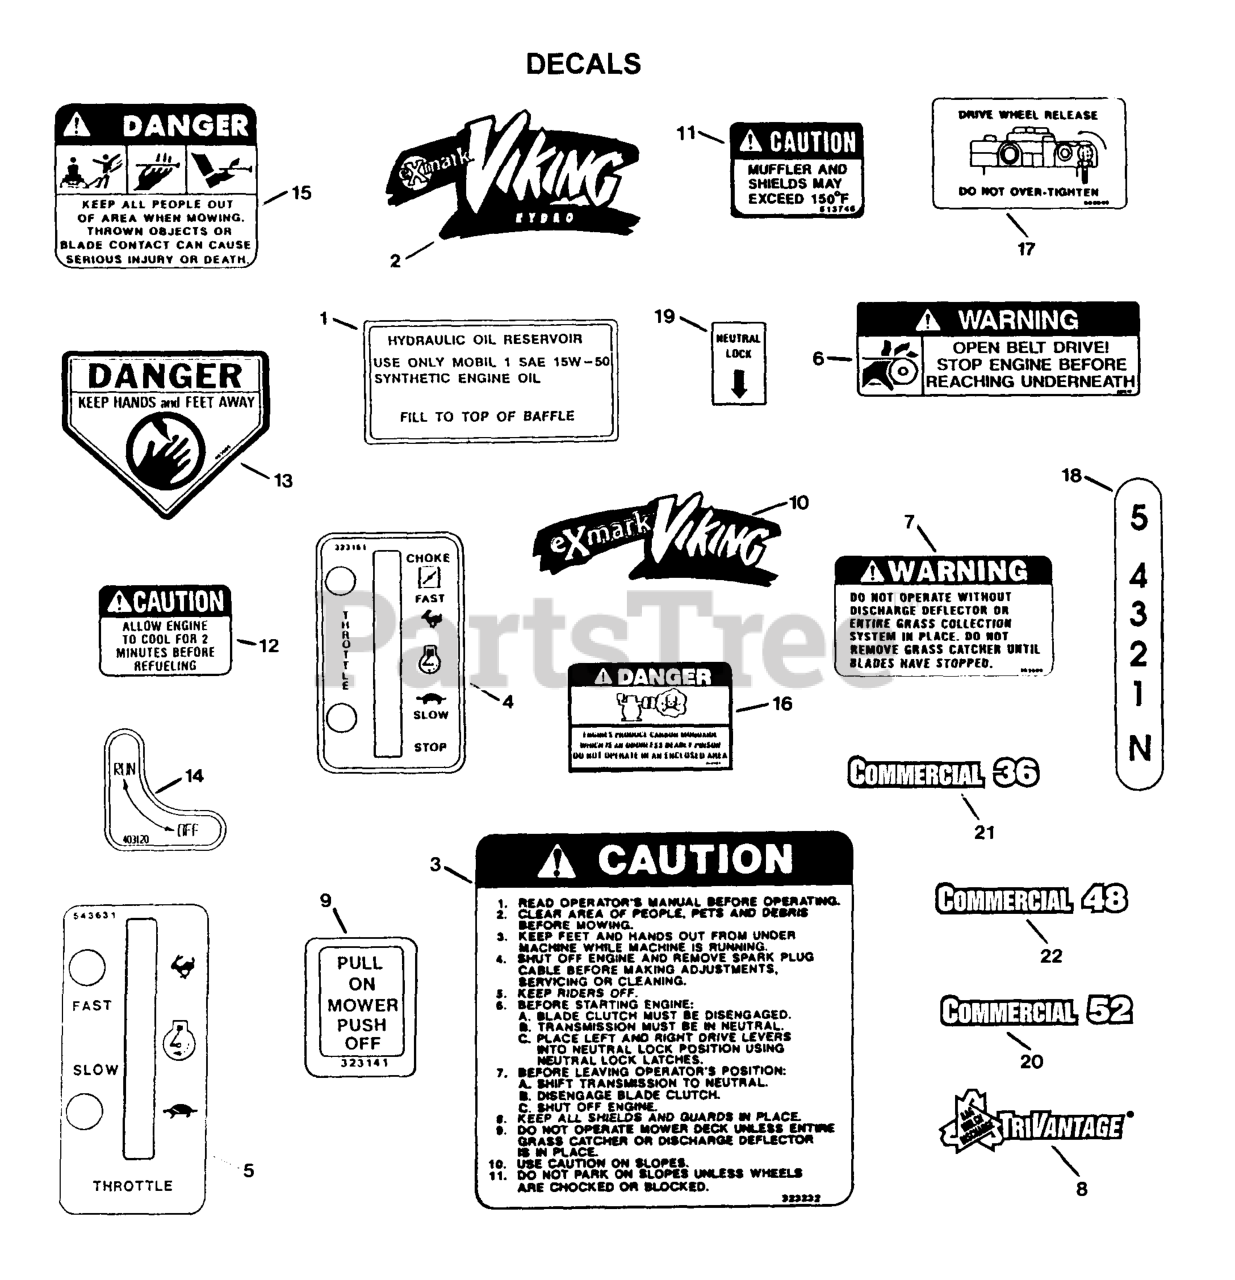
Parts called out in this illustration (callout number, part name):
1	DECAL,HYD TANK
3	DECAL,INSTRUCTIONAL
6	DECAL,BELT DRIVE
7	DECAL-WARNING, DISCHARGE
13	DECAL-DANGER
15	DECAL-DANGER
17	DECAL,DRIVE RELEASE
18	DECAL - SHIFTER
19	DECAL,NEUTRAL LOCK
20	DECAL,COMMERCIAL 52
21	DECAL,COMMERCIAL 36
22	DECAL,COMMERCIAL 48
